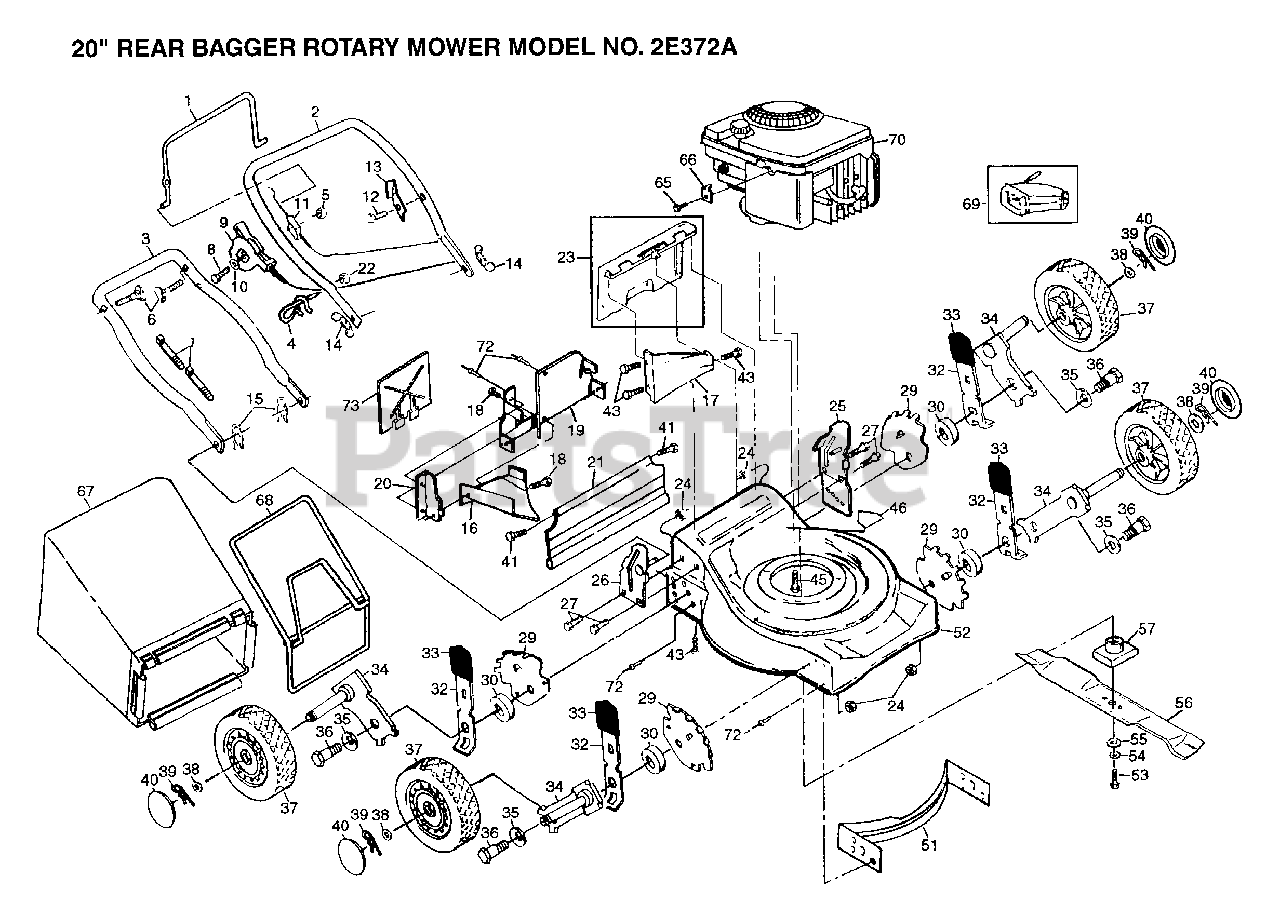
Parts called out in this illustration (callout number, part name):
1	CONTROL BAR
4	ROPE GUIDE
6	BOLT.HANDLE.LM
9	CNTL.THROT.47.5
10	WASHER PM
11	"CABLE,ENG ZONE CO"
12	TAPPING SCREW
13	"BRKT,UPSTOP"
14	"NUT,WING PM"
15	HAIRPIN COTTER
16	DISCHARGE GUARD
17	REAR BAFFLE
18	SCREW PM
19	PLATE.BACK.20RD
22	NUT
23	"KIT, REAR DOOR PM"
24	LOCKNUT PM
27	SCREW
29	BRACKET.ADJ.9POS.
32	SPRING SELECTOR
33	KNOB PM
34	AXLE ARM
35	"WASHER, BELLEVIL."
38	WASHER
39	RETAINER CLIP PM
40	HUB CAP
41	HINGE SCREW
43	SCREW
45	SCREW
46	DECAL HYT
52	KIT.HSG.20RD
53	SCREW
54	LOCKWASHER
55	"WASHER,HARDEN"
57	BLADE ADAPTOR
65	SCREW PM
66	CABLE CLAMP
67	GRASS BAG
68	CATCHER FRAME
72	BLIND RIVET
73	MULCHER PLATE
